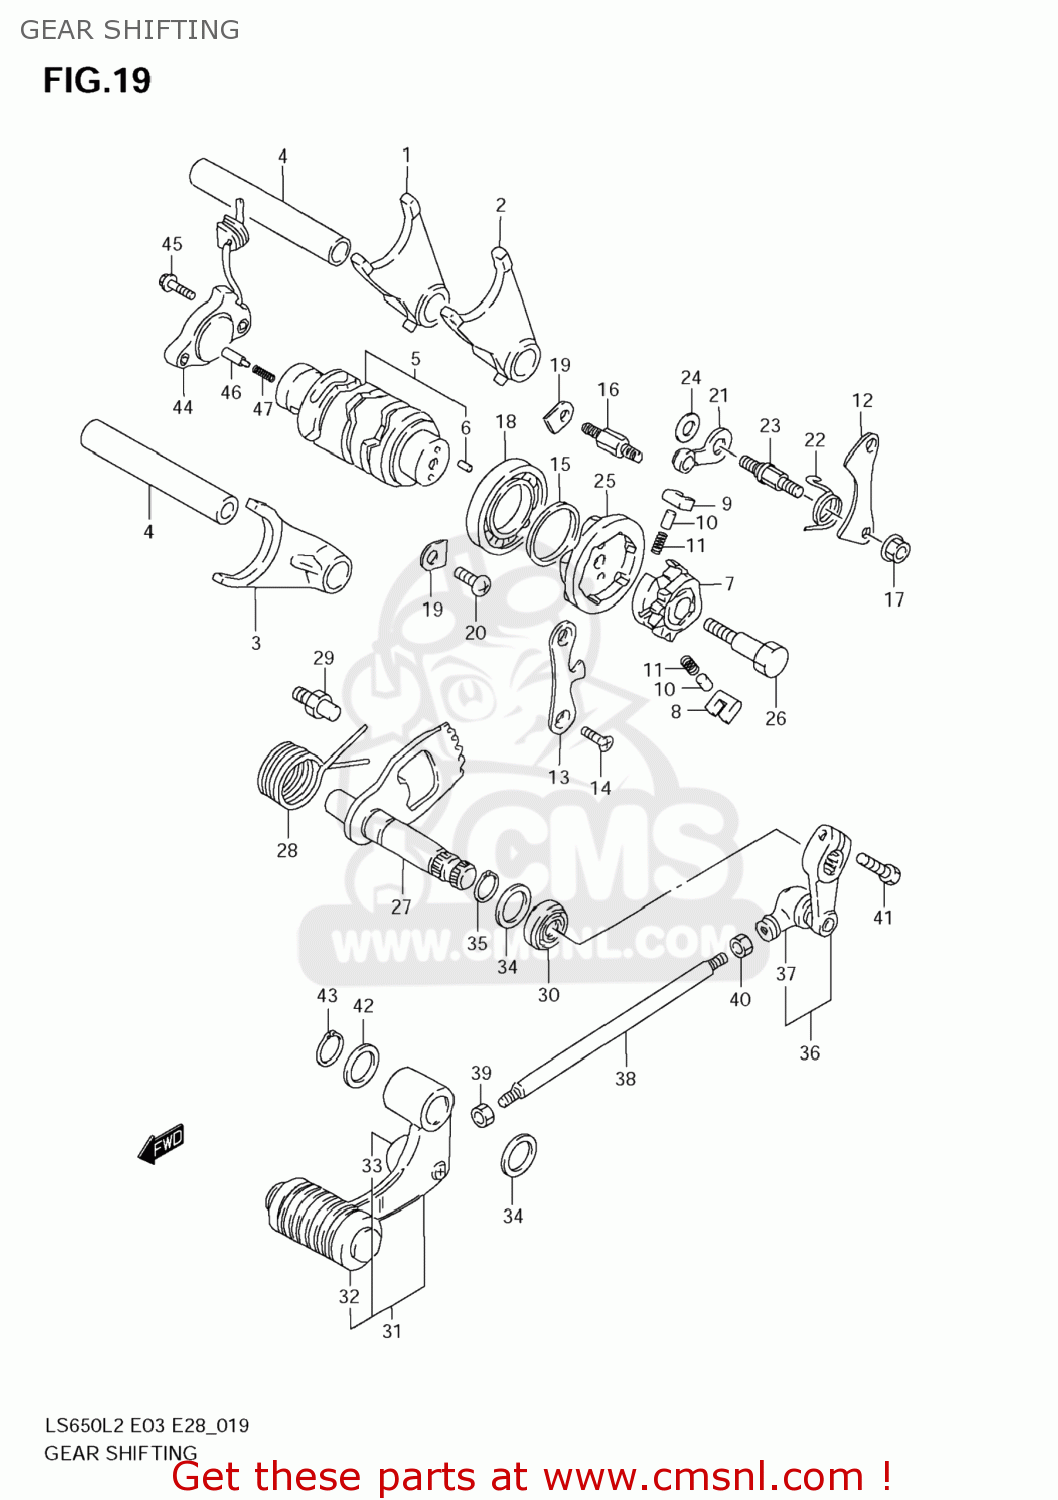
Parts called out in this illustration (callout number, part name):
1	FORK,GEAR SHIFT NO.1
2	FORK,GEAR SHIFT NO.2
3	FORK,GEAR SHIFT NO.3
4	SHAFT,GEAR SHIFT FORK
5	CAM,GEAR SHIFT
6	PIN
7	GEAR,GEAR SHIFT CAM DRIVEN
8	PAWL,GEAR SHIFT NO.1
9	PAWL,GEAR SHIFT NO.2
10	PIN(5X8)
11	SPRING
12	LIFTER,GEAR SHIFT POLE
13	GUIDE,GEAR SHIFT CAM
14	SCREW
15	WASHER(25X32X3)
16	BOSS,SHIFT PAWL LIFTER
17	NUT
18	BEARING(25X47X8)
19	RETAINER
20	SCREW
21	STOPPER,GEAR SHIFT CAM
22	SPRING
23	SUPPORT,CAM STOPPER ARM
24	WASHER
25	PLATE,GEAR SHIFT CAM
26	PIN,SHIFT CAM DRIVEN GEAR
27	SHAFT,GEAR SHIFT
28	SPRING
29	STOPPER,GEAR SHIFT ARM
30	SEAL,OIL (12X22X9)
31	LEVER ASSY,GEAR SHIFT
32	RUBBER,GEAR SHIFT PEDAL
33	COVER,DUST
34	WASHER(12.5X20X1)
35	CIRCLIP
36	ARM,GEAR SHIFT LINK
37	COVER,DUST
38	ROD,GEAR SHIFT LINK
39	NUT
40	NUT
41	BOLT
42	WASHER
43	CIRCLIP
44	BASE ASSY,NEUTRAL SW TERMINAL
45	SCREW
46	PIN(5X15.5)
47	SPRING
